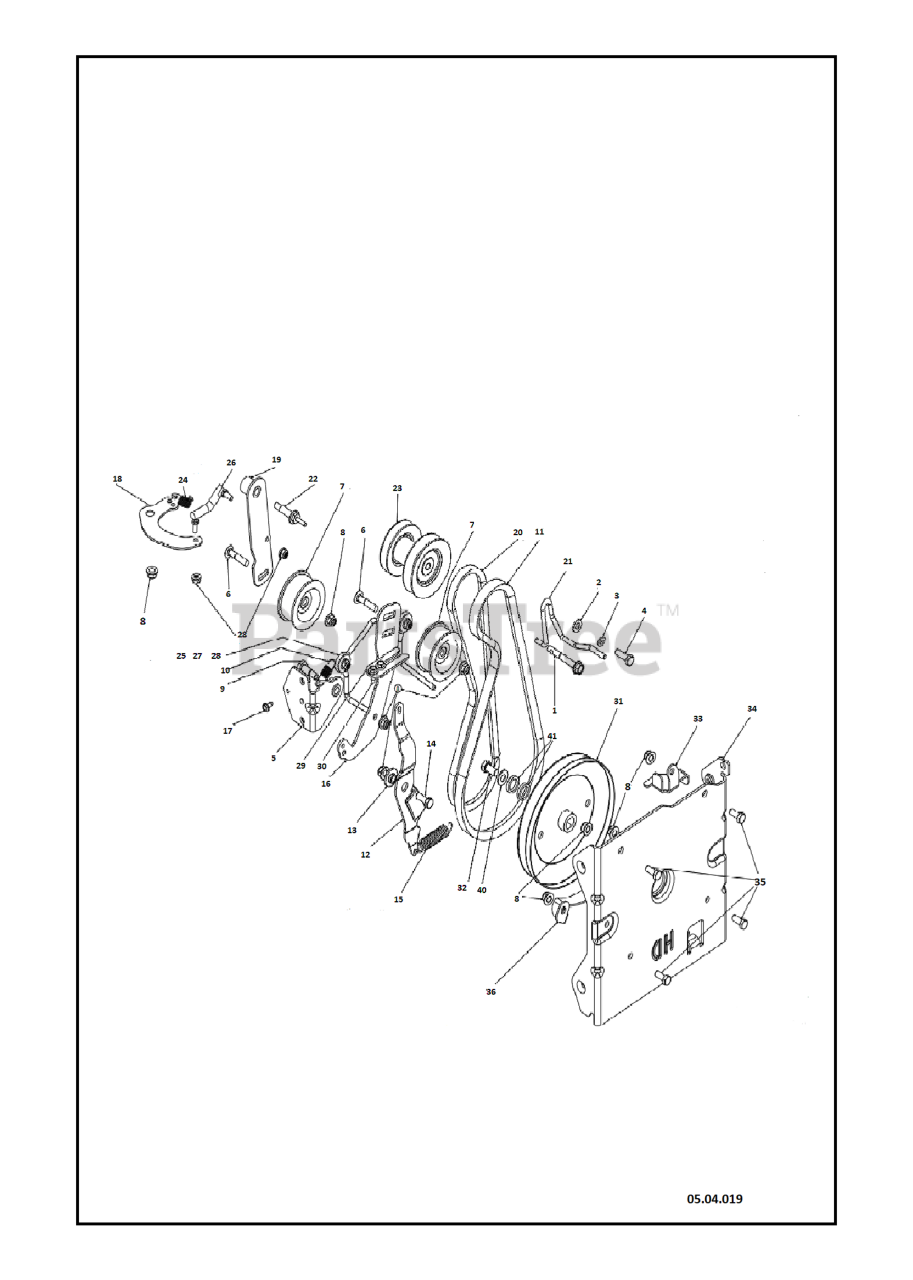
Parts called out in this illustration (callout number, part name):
2	WASHER 11/32 X 11/16 X 14 GA T
3	WASHER SPRING LOCK WASHER WITH
5	BRACKET WELDMENT, IDLER ARM ZI
6	BOLT 5/16-18 CARRIAGE 1.5L
8	NUT HEXAGON FLANGE 5/16-18 ST
9	SCREW HEX HEAD SHOULDER
10	SPRING IDLER RETURN
11	BELT 5L 39.15L
12	ARM IMPELLER BRAKE
13	BUSHING.BRAKE.ARM
14	BOLT HEXAGON BOLT 5/16-18 X 7/
15	SPRING EXTENSION - BRAKE
16	ARM IDLER BLACK ZINC
18	Bell Cranks
19	ARM DRIVE IDLER BLACK ZINC PLA
20	BELT 4L DRIVE
21	Belt Keepers
22	GUIDE BELT, SHOULDER SCREW
23	PULLEY 5L HYDRO
24	SPRING EXTENSION - DRIVE
25	GUIDE BELT - HYDRO 2 WITH FAN
26	LINK ASSY DRIVE IDLER
28	NUT FLG, NYLOCK, 1/4-20 GR G C
30	HEX.WASHER.HEAD 1/4-20 X .65
31	PULLEY IMPELLER DD 5L HD
32	SCREW HEXAGON HEAD FLANGE 3/8-
34	BRACKET AUGER HOUSING INTERFAC
35	SCREW HEXAGON HEAD SCREW 5/16-
36	BRACKET.BELT.KEEPER.LOWER.BLAC
40	WASHER PLAIN WASHER 3/8 X 0.08
41	WASHER.SPACER.MANDREL
